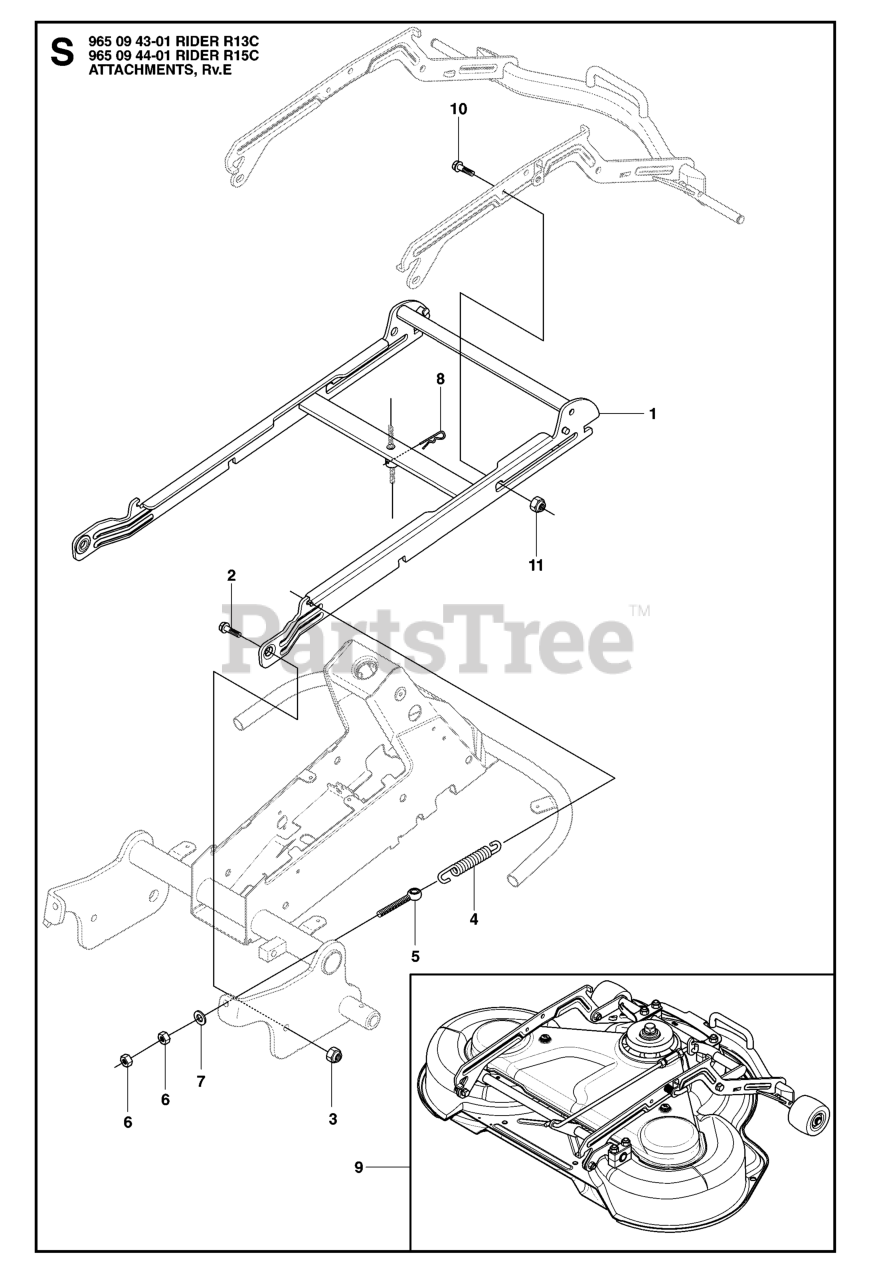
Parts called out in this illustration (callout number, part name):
6	NUT
7	WASHER
10	COLLAR SCREW
11	LOCKNUT M8
